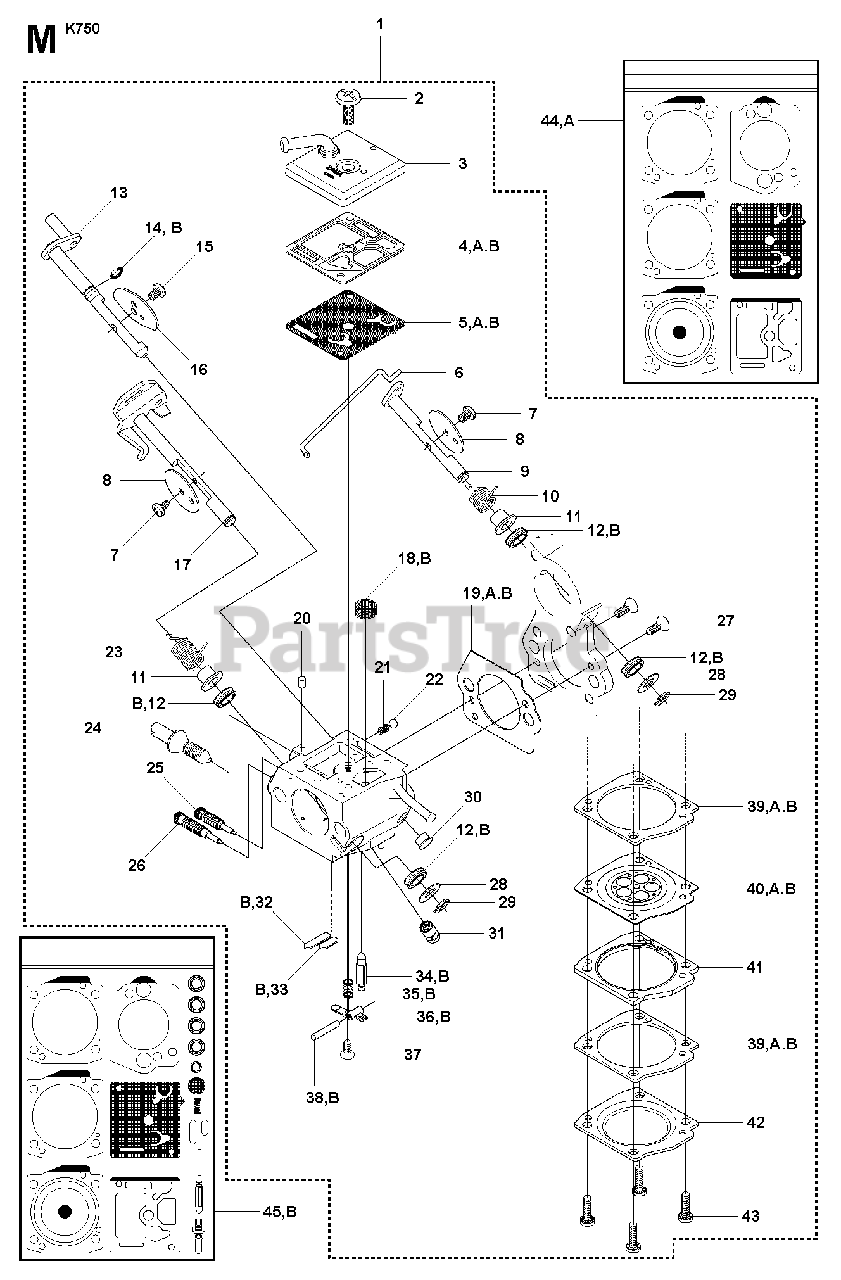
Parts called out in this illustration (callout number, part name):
1	CARBURETTORZama C3-EL29, Incl. 2 - 43
5	DIAPHRAGM PUMP
38	PIN RETAINING SCREW
40	DIAPHRAGM ASSY
44	GASKET KITIncl. 4, 5, 19, 39, 40
45	GASKET KITIncl. 4, 5, 12, 14, 32 - 36, 38 - 40
